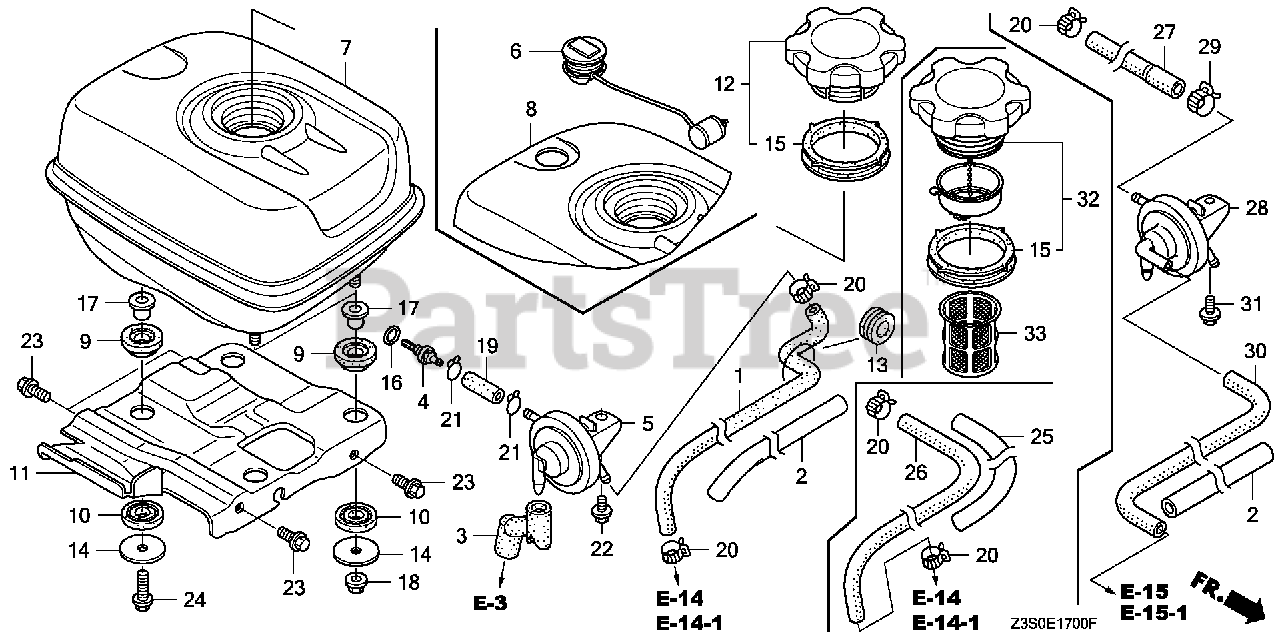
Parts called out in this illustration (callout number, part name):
13	RUBBER, RR. FENDER CUSHION
20	CLAMP, TUBE (D8)
25	RUBBER, SUPPORTER
26	TUBE, FUEL (4.5X580) (FKM)
